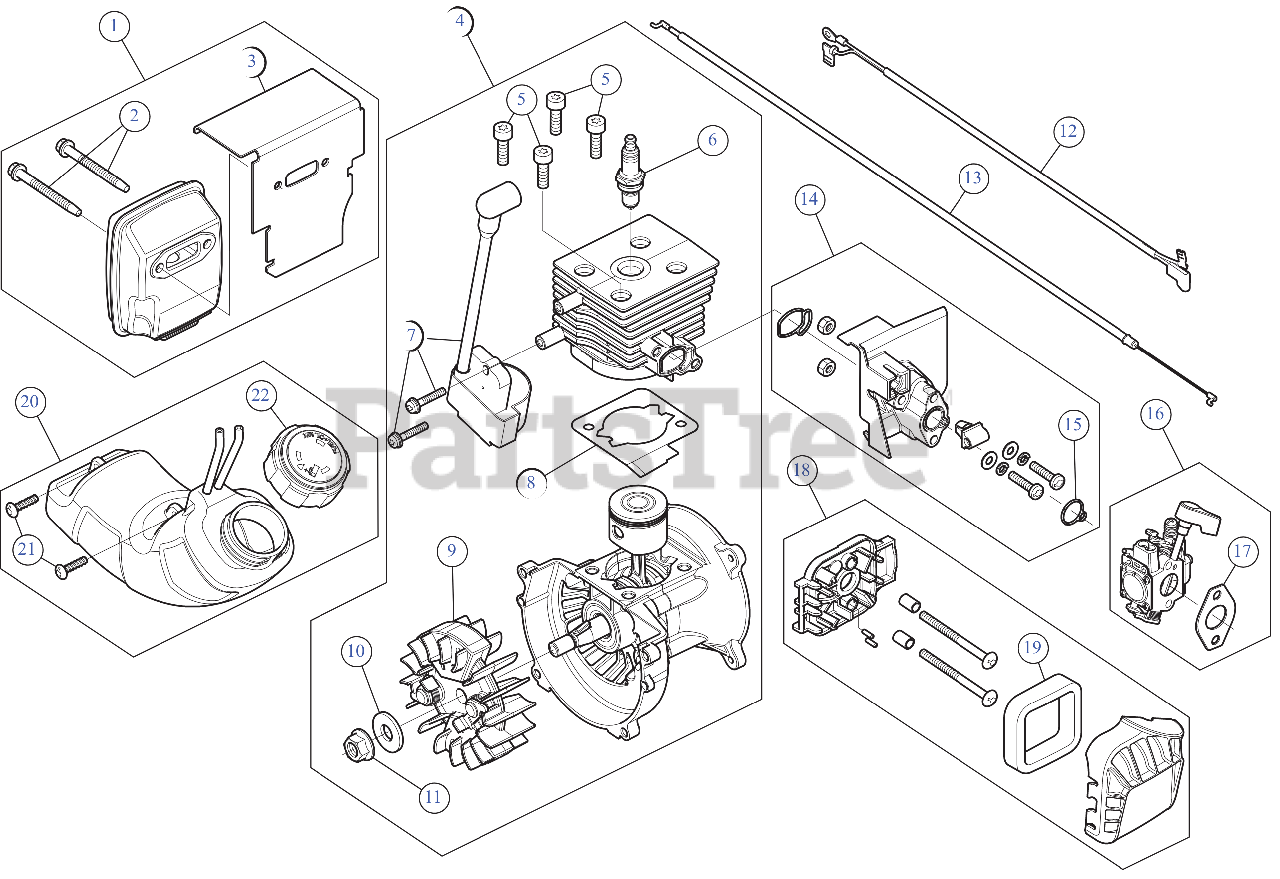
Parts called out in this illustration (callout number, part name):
1	MUFFLER ASSEMBLY 27CC
2	MUFFLER SCREW
3	MUFFLER GASKET
4	SHORT BLOCK
5	SCREW 1/4 x 20 x .8125
6	SPARK PLUG
7	MODULE ASSEMBLY
8	GASKET CYL
9	FLYWHEEL ASSEMBLY
10	WASHER .406X1.0X.095
11	NUT 3/8-24
12	LEAD WIRE
13	THROTTLE CABLE
14	INTAKE ASSEMBLY
15	O-RING
16	CARBURETOR ASSEMBLY
17	GASKET CARB
18	AIRCLEANER ASSEMBLY
19	AIR FILTER
20	FUEL TANK ASSEMBLY
21	SCREW 8-16 x 3/4
22	ASSEMBLY, FUEL CAP (RED TOP)
